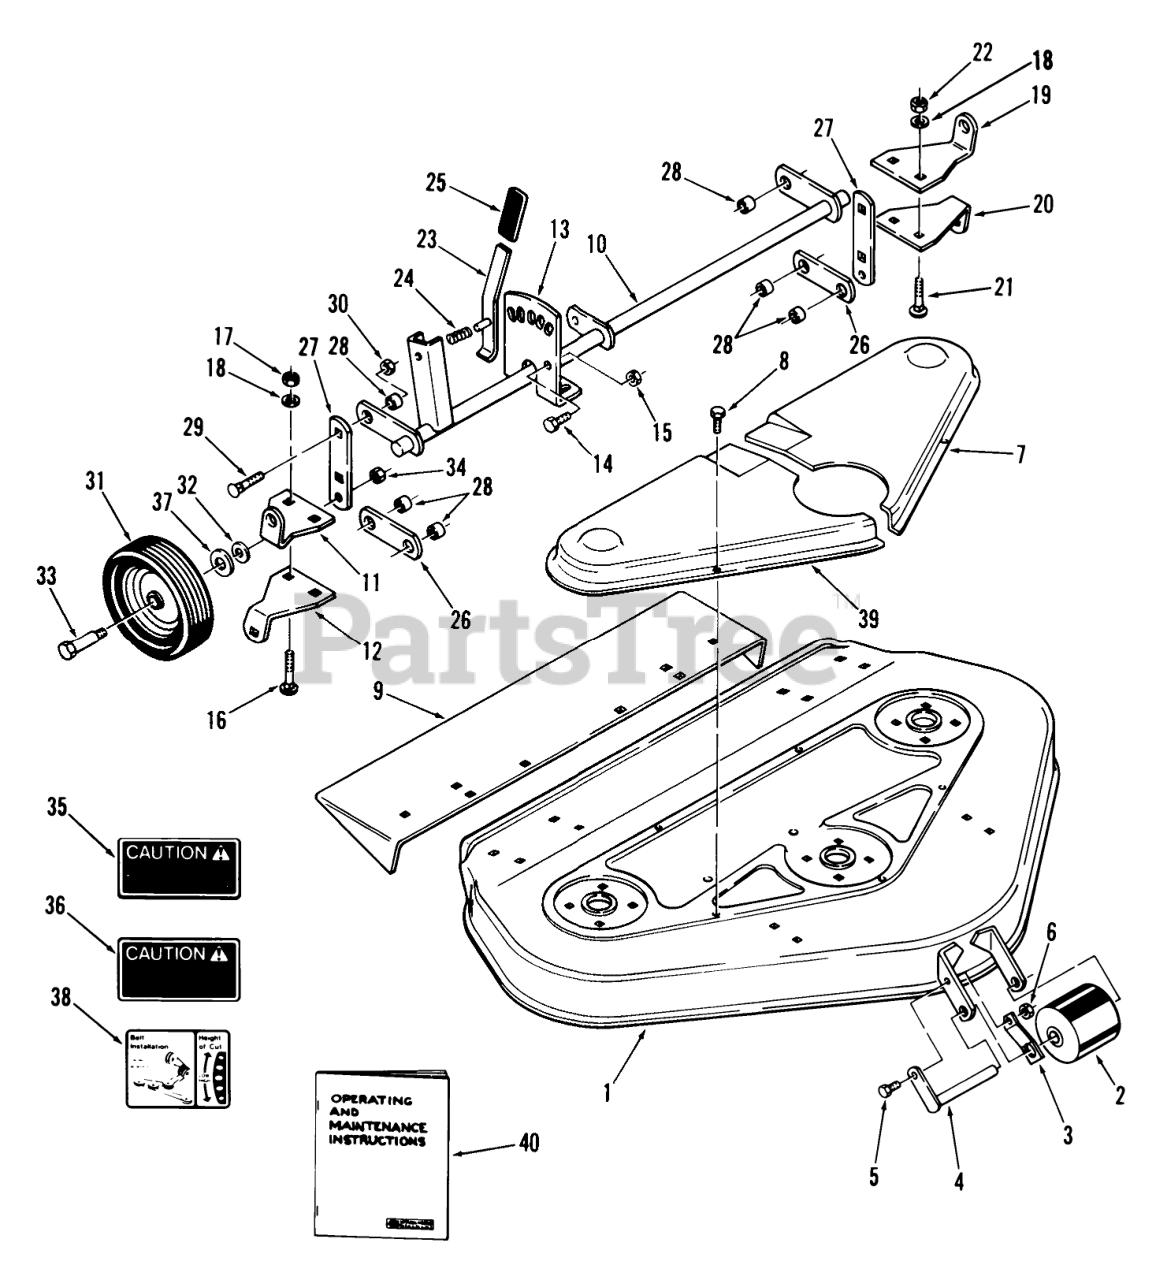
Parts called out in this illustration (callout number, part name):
1	Mower Deck-Rear Discharge
1	Mower Deck-Side Discharge
2	Roller
3	SPRING ROLLER STOP
4	Roller Shaft
5	H H C S
6	Nut
7	Belt Cover L.H.
8	Bolt
9	Extension-Chute
10	Gage Wheel Support Assy.
11	Bracket-R.H. Upper
12	Bracket-Lower R.H.
13	Quadrant
14	Bolt
15	Nut
16	Bolt
17	Nut
18	Washer
19	Bracket-L.H. Upper
20	Bracket-L.H. Lower
21	Bolt
22	Nut
23	Lever
24	SPRING-COMPRESSION
26	SUPPORT LINK R
27	WHEEL SUPPORT LINK
28	SPACER
29	Bolt
30	LOCKNUT-FLANGE
31	Wheel 6 x 1.75
32	WASHER
33	BOLT-SHOULDER
34	Nut
35	Caution Decal
36	Decal-Caution
37	WASHER
38	DECAL-HEIGHT & BELT
39	Belt Cover R.H.
40	Operating and Maintenance Instructions
